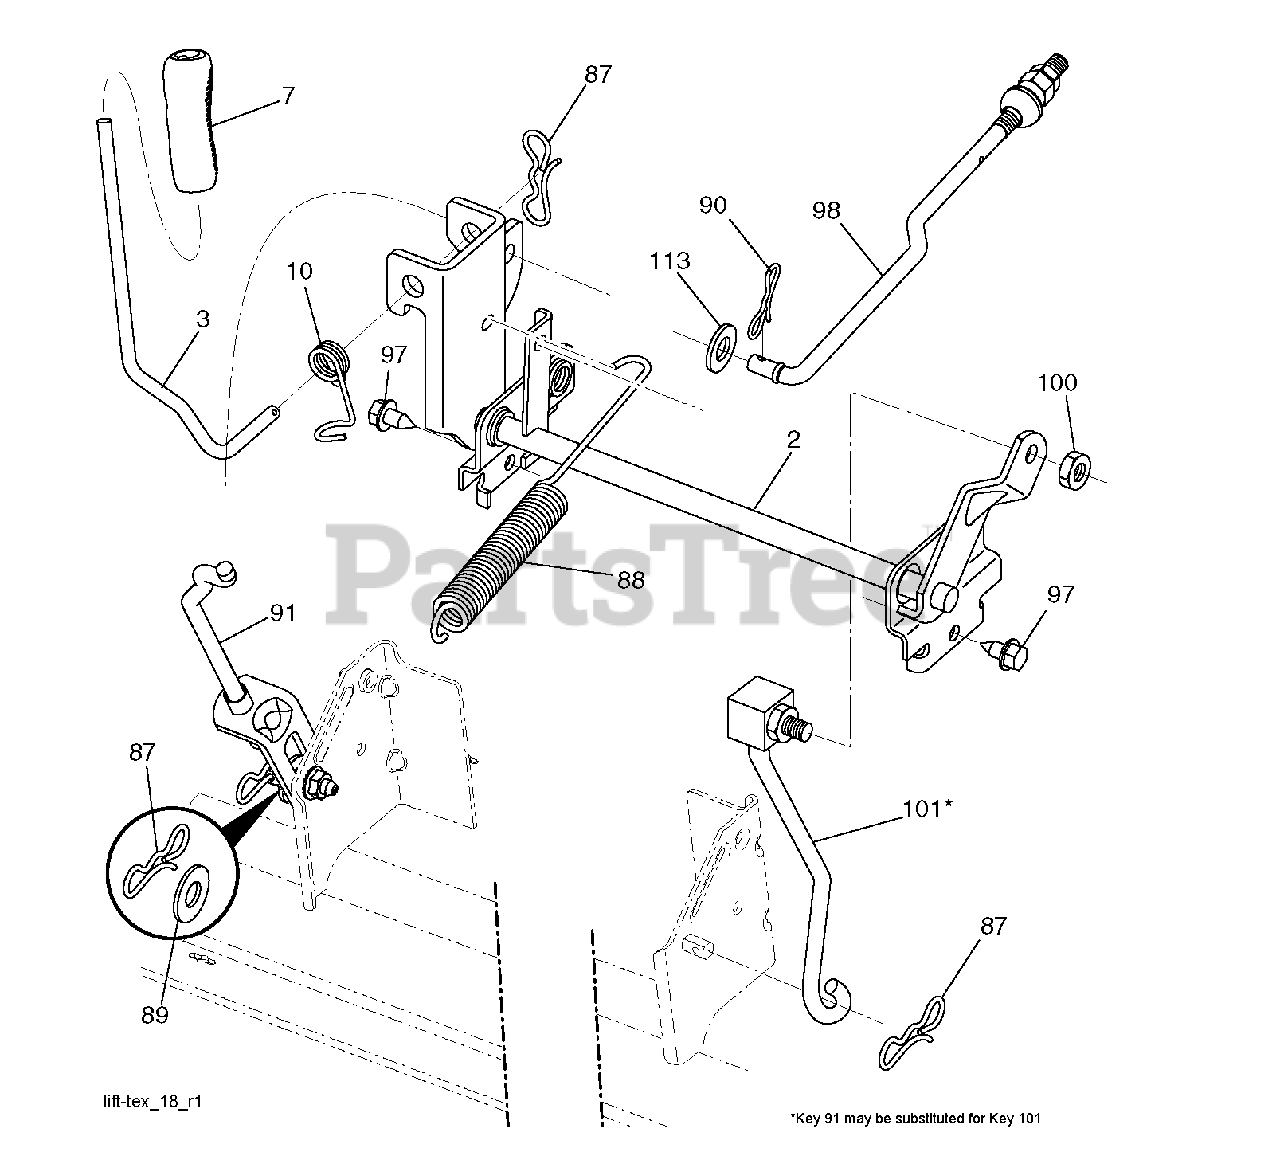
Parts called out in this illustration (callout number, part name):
2	SHAFT.ASM.CROSS.LIFT
3	LEVER.LIFT.HANDLE.LT
7	GRIP.HANDLE.LIFT.PVC.BLACK
10	SPRING.TORSION.LIFT.HANDLE
87	PIN.COTTER.7/16.BOW TI
88	SPRING.LIFT.ASSIST
90	PIN.COTTER.5/16.BOW TI
91	LINK.ASM.LIFT.REAR
97	SCREW, 3/8-16X3/4
98	LINK.ASM.SUSP.FRONT.MWR.10.5
100	LOCKNUT
101	LINK.ASM.LIFT.FIXE.38/42/46"
113	WASHER.CLEAR.ZINC
